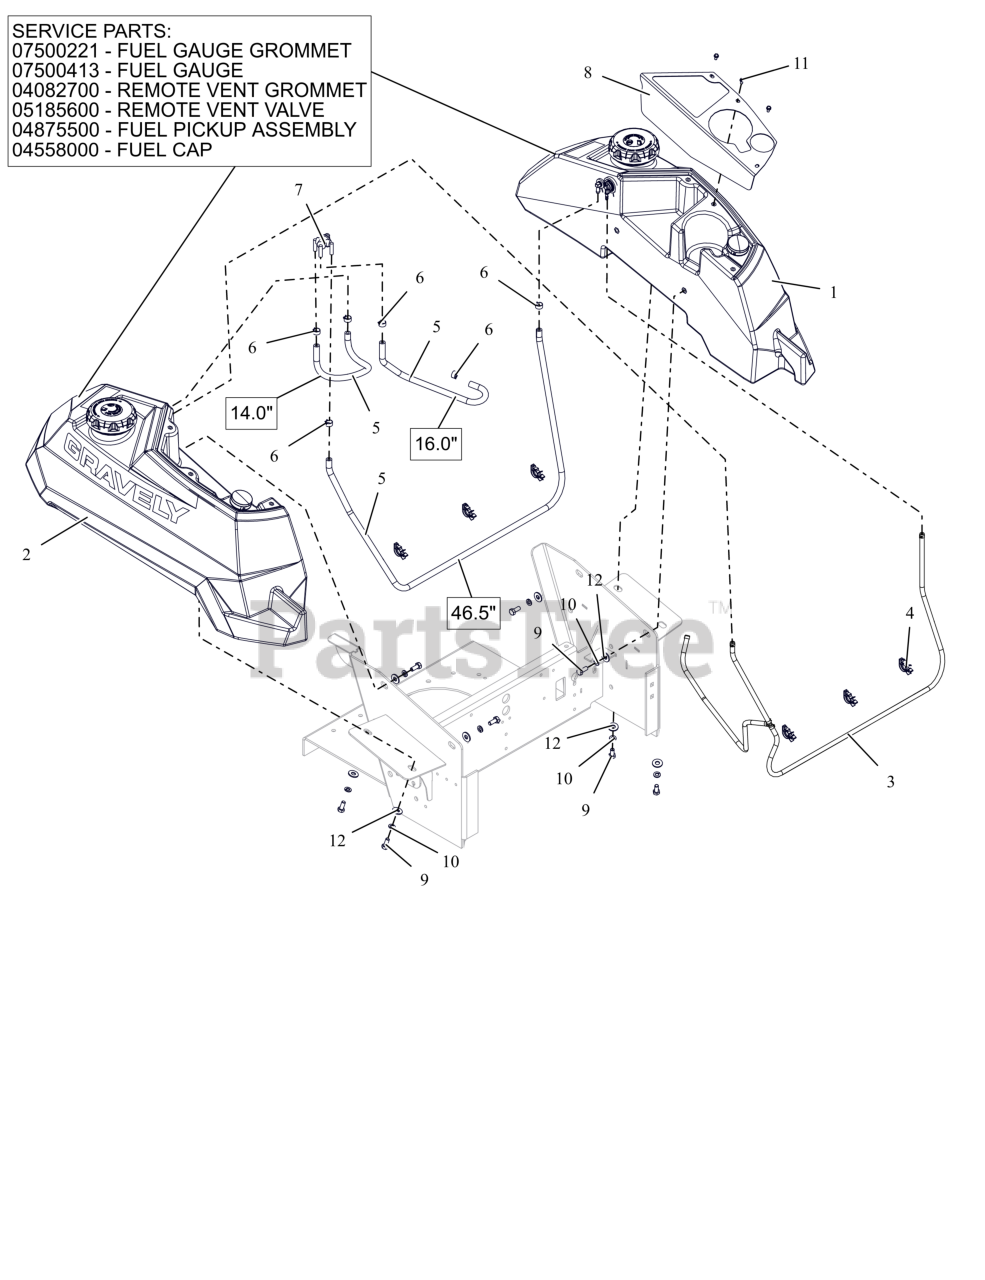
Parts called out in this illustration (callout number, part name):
1	ASM, LH - PT100 FUEL TANK
1	GROMMET, FUEL GAUGE
1	GAUGE, REMOTE SEALED FUEL
1	GROMMET, REMOTE VENT NITRILE
1	VALVE, COMBINATION VENT 3/16
1	ASSM,LRG TANK FUEL PICKUP LINE
1	CAP, FUEL VENTIN AUTOLOCK
2	ASM, RH - PT100 FUEL TANK
2	GROMMET, FUEL GAUGE
2	GAUGE, REMOTE SEALED FUEL
2	GROMMET, REMOTE VENT NITRILE
2	VALVE, COMBINATION VENT 3/16
2	ASSM,LRG TANK FUEL PICKUP LINE
2	CAP, FUEL VENTIN AUTOLOCK
3	ASM, VAPOR LINE
4	WIRE CLIP
5	1 INCH OF HOSE, .25 LOW-PERM BULK GAS
6	CLAMP, FUEL LINE
7	VALVE, FUEL
8	PT100 CUPHOLDER PANEL - RED
9	BLT,HEX .31-18X.75 G5 ZCC
10	WSHR,LK-REG .312X.078 ZCC
11	SCR-MCH 10-24X.38 HWHSTAINLESS
12	WSHR,FLT .375X.875X.083 ZCC
